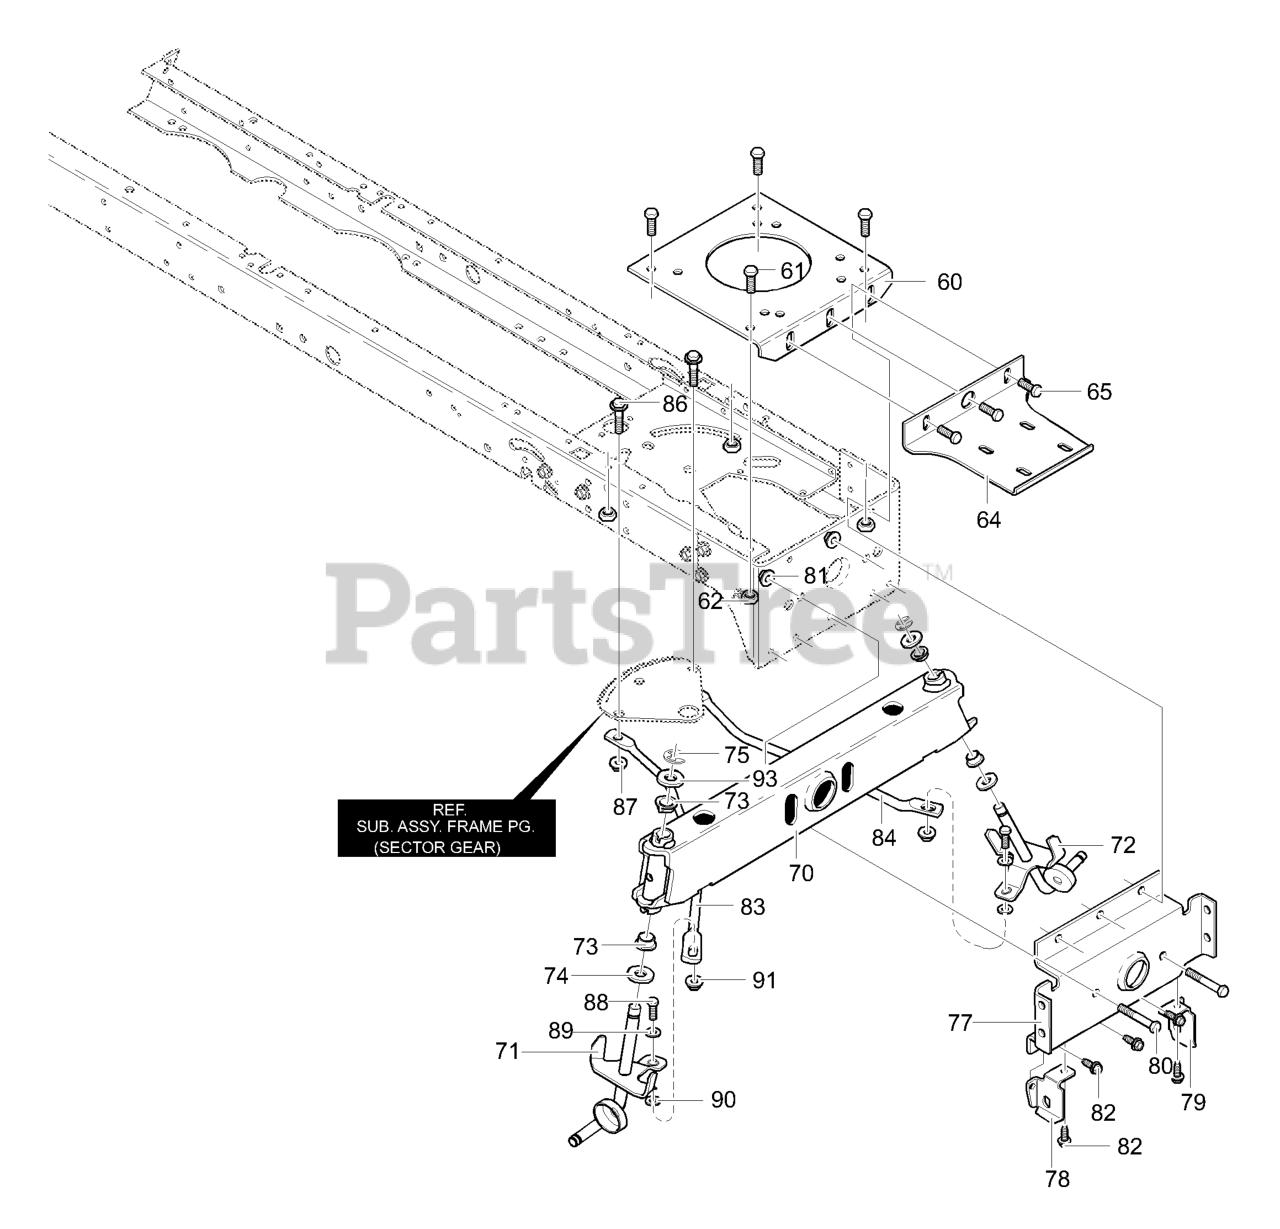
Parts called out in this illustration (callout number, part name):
60	Engine Plate
61	Screw, .312-18x.75
62	Nut, 5/16-18
64	Bracket, Muffler Mount
65	Screw, .312-18x.75
70	Axle, Cast Machined
71	Spindle, RH
72	Spindle, LH
73	Bearing, Spindle
74	Washer, .766IDx1.62ID
77	Hanger, Axle
78	Hanger, Deck RH
79	Hanger, Deck LH
80	Screw, 5/16-24 x 2.75
81	Nut, .32-24 Flangelock
82	Screw, .5/16-24X2.75
83	Drag Link, RH
84	Drag Link, LH
86	Shoulder Bolt
87	Nut, 3/8-16
88	Screw, 3/8-16 x 1.50
89	Flatwasher
90	Flatwasher
91	Nut, 3/8-16
93	Flat washer
